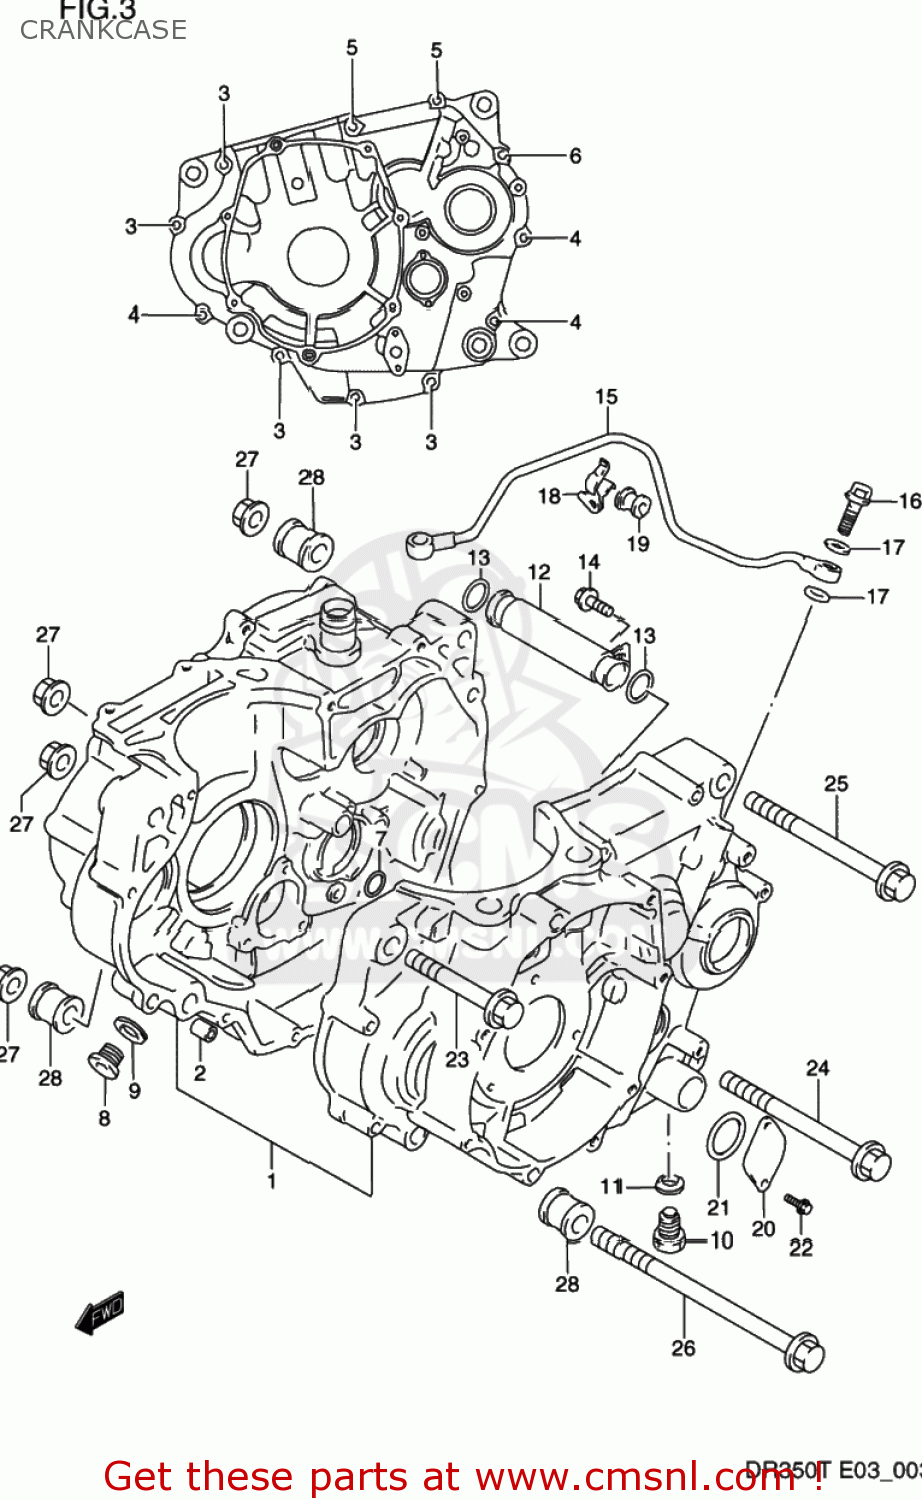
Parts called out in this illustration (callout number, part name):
1	CRANKCASE SET
2	PIN
3	BOLT
4	BOLT
5	BOLT
6	BOLT
7	O-RING
8	PLUG,14X12
9	GASKET(13.8X18.8X4.8) (NAS)
10	BOLT
11	GASKET(12.1X16.2X3.7) (NAS)
12	PIPE,T/M OIL INNER
13	O RING(D:2.4,ID:15.8)
14	BOLT
15	PIPE,T/M OIL OUTER
16	BOLT UNION
17	GASKET 8.2X14X1 (NAS)
18	CLAMP,OIL PIPE
19	CUSHION
20	CAP,NEUTRAL SWITCH HOLE
21	O RING(D:2.4,ID:26.2)
22	BOLT
23	BOLT 10X85
24	BOLT
25	BOLT(10X115)
26	BOLT
27	NUT
28	SPACER,ENGINE MOUNT
